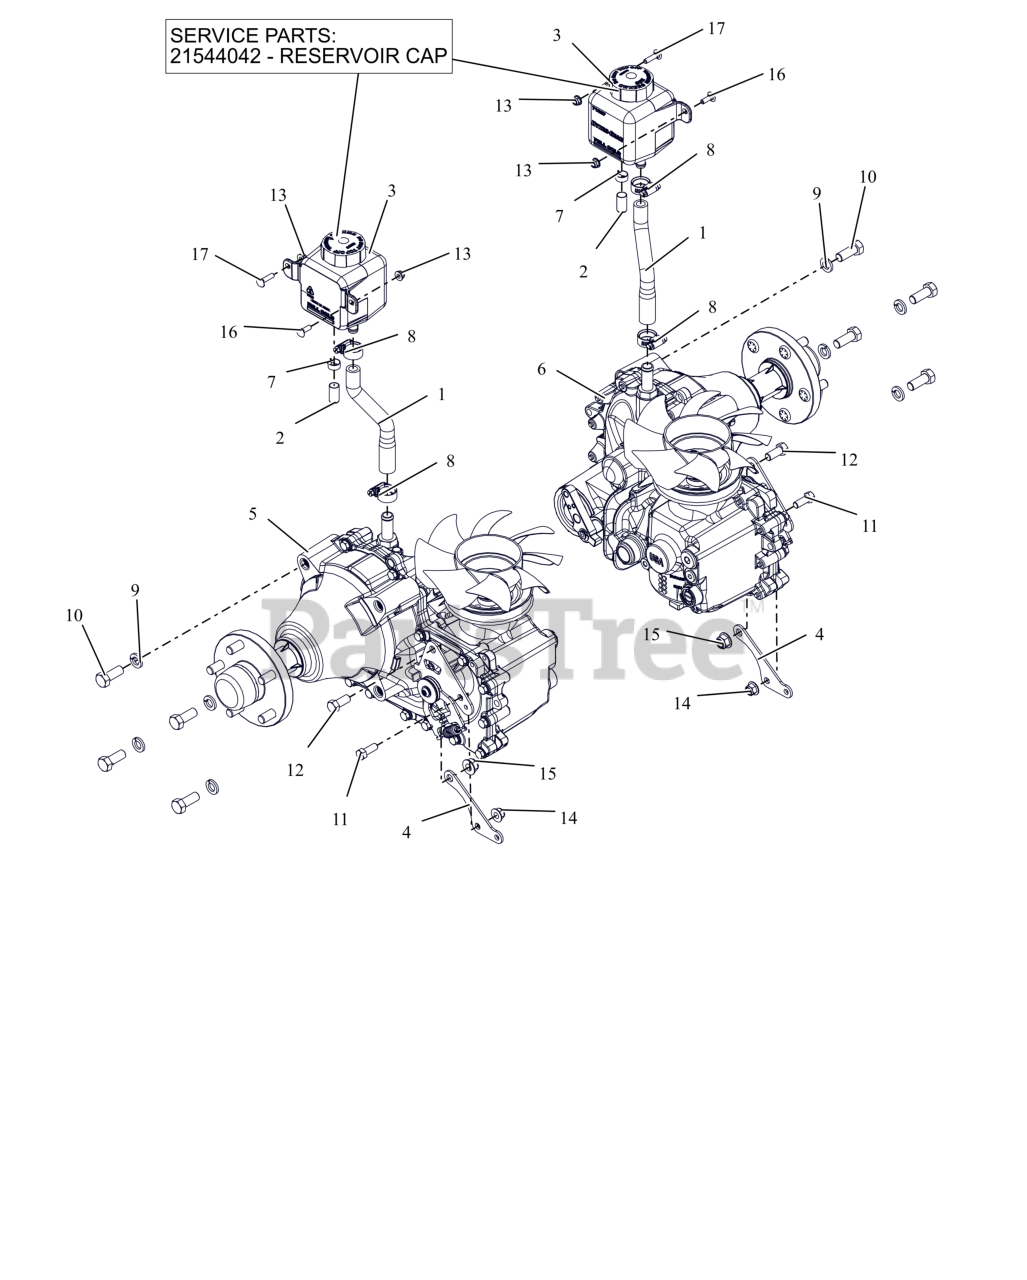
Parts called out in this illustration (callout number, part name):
1	HOSE,PT200/400 TRANS OVERFLOW
2	CAP, .50 BARBED FITTING
3	TANK, HYDRO OVERFLOW 700 ML
3	CAP, HYDRO RESERVOIR REPLAC.
4	DRV CNTRL LINKAGE MTG BRKT-BLK
5	TRANSAXLE, RH HG ZT-5400
6	TRANSAXLE, LH HG ZT-5400
7	CLAMP, .62 SPRING
8	CLAMP,.88 DIA. HOSE
9	WSHR,LK-REG .500X.125 ZCC
10	BLT,HEX .50-13X1.25 G5 ZCC
11	BLT,HEX .38-16X1.00 G5 ZCC
12	BLT, HEX 0.4375-14X1 GR5 ZCC
13	NUT,NYL-FLG .25-20 GF ZCC
14	NUT,NYL-FLG .38-16 GF ZCC
15	NUT,NYL-FLG .44-14 GF ZCC
16	BLT, RHSN .25-20X.750 G5 ZCC
17	BLT, RHSN .25-20X1.00 G5 ZCC
